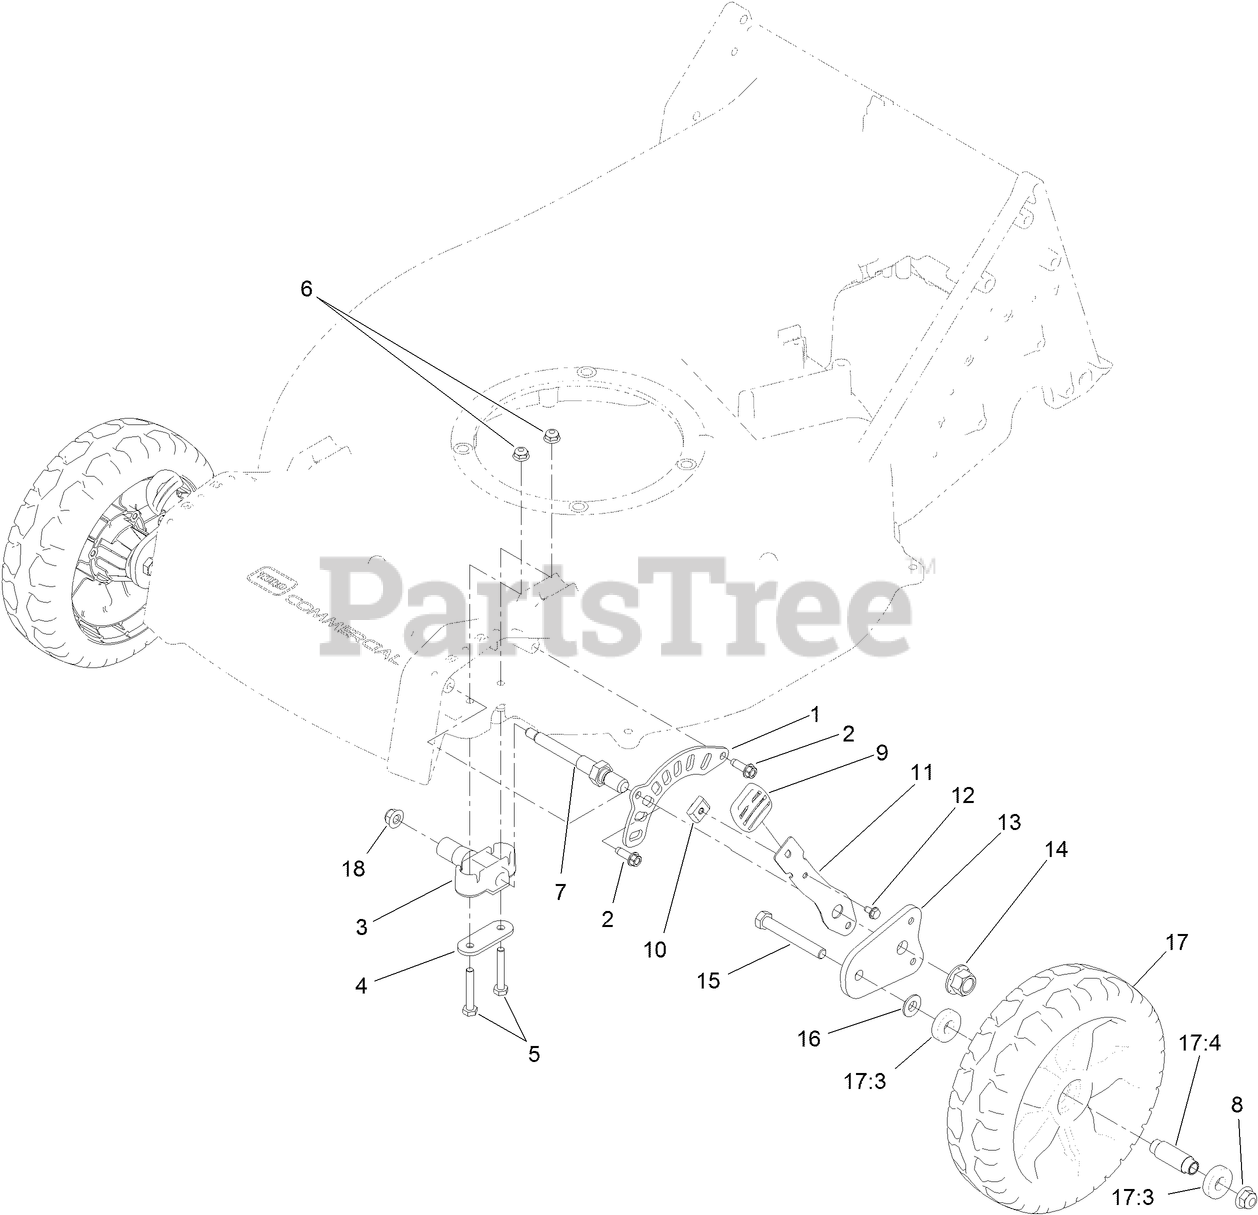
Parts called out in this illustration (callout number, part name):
1	PLATE-HOC, FRONT
2	SCREW-HWHTF
3	BUSHING-AXLE, FRONT (HOC)
4	RETAINER-BUSHING, AXLE
5	SCREW-HH
6	NUT-HF
7	AXLE-FRONT HOC
8	NUT-HF, NI
9	KNOB-LEVER, HOC
10	KEY-ARM, SPRING
11	ARM-SPRING
12	SCREW-HWH
13	ARM-PIVOT, FRONT
14	NUT-LOCK
15	SCREW-HH
16	SPACER-COVER, WHEEL
17:3	BEARING-BALL
17:4	SPACER
18	NUT-HF, NI
